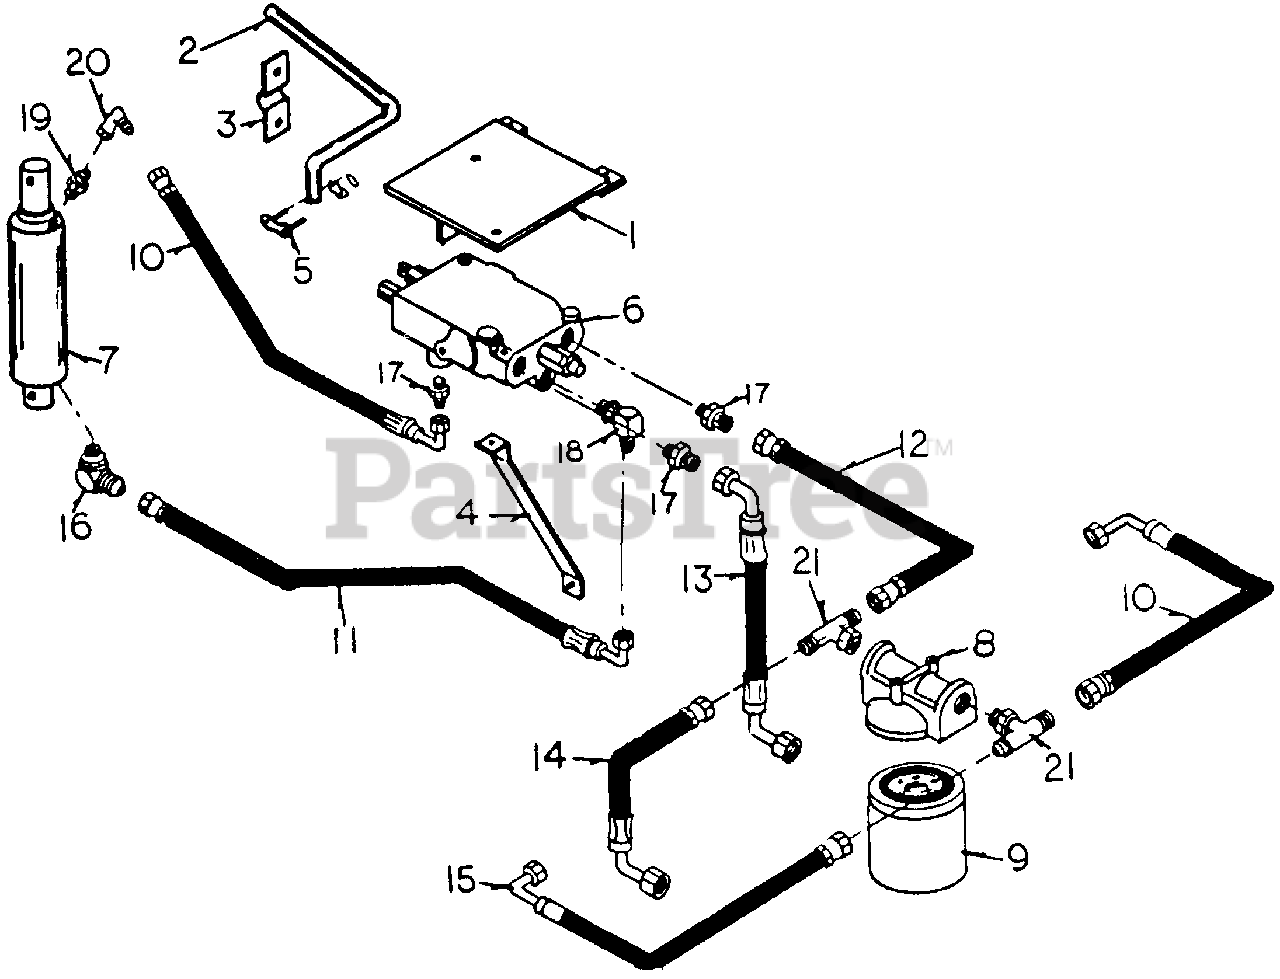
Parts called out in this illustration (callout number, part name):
1	Valve Mount
3	Bearing, Clutch Brake 1 0 Cross Ro
4	Valve Support
5	Connecting Link, #50
8	Housing, Oil Filter
9	Element, Oil Filter
10	Hose, 3/8" ID x 26" Long
11	Hose, 3/8" ID x 31" Long
12	Hose, 3/8" ID x 20" Long
13	Hose, 3/8" ID x 13" Long
14	Hose, 3/8" ID x 11.5" Long
15	Hose, 3/8" ID x 21" Long
16	Male O-ring, 90ø Male 1 Tube Adp.
17	Male O-ring, Male 3 Tube Adp.
18	Male O-ring, 90ø Male Tube Adp.
19	Male O-ring, Male 1 0 Tube Adp.
20	Male Tube, 90ø 37ø 1 Female Swivel Adp.
21	Ma le Tube, Ma le O-ring 2 Tee
